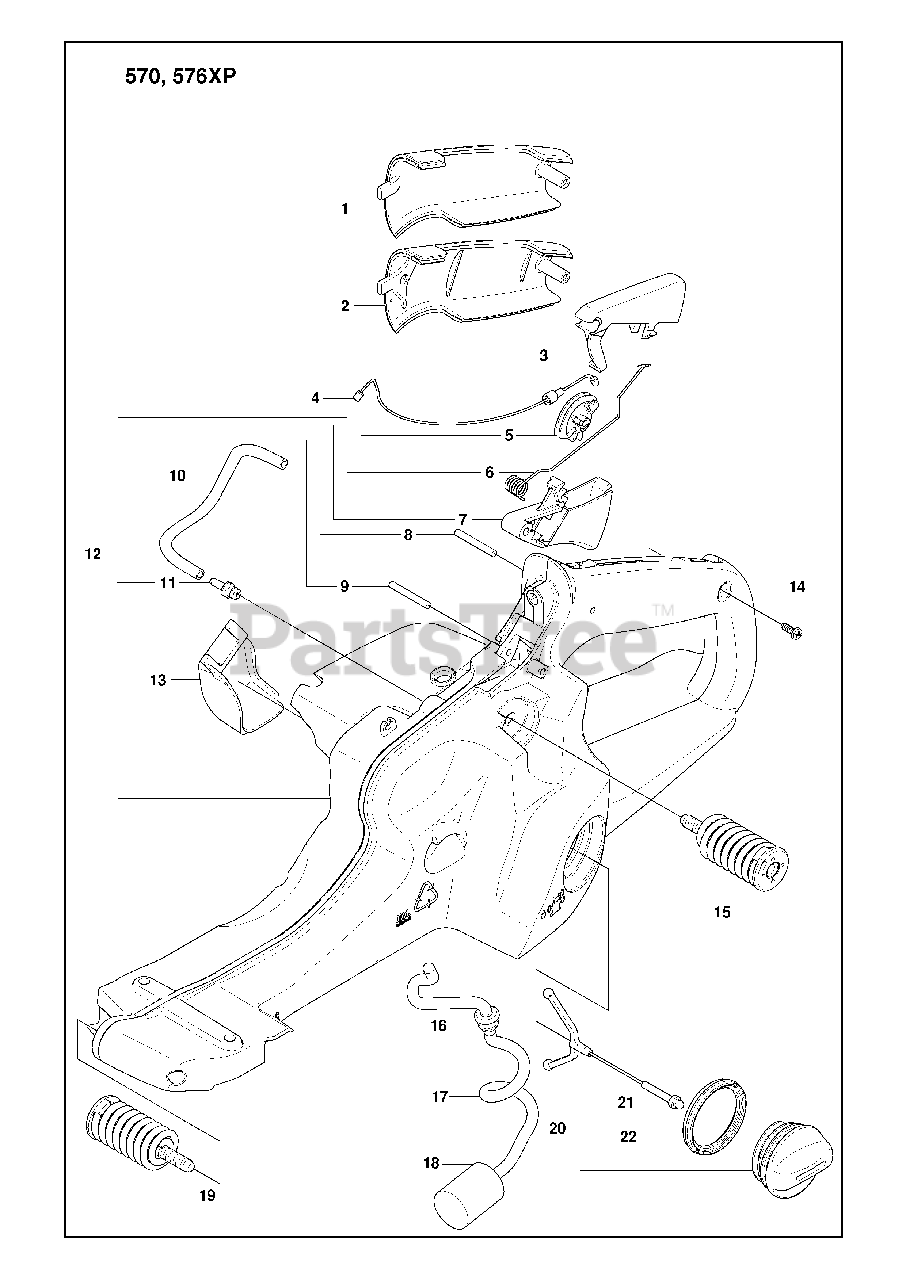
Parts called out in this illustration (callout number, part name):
1	COVER
2	COVER
3	THROTTLE LOCK
4	THROTTLE WIRE
7	THROTTLE TRIGGER
8	PIN 3X25
9	PIN 3X25
10	HOSE
11	FUEL TANK VENT
15	VIBRATION ABSORBER
16	FUEL TANK BUSHING
17	FUEL HOSE
18	FUEL FILTER
19	VIBRATION ABSORBER
20	TANK CAP
